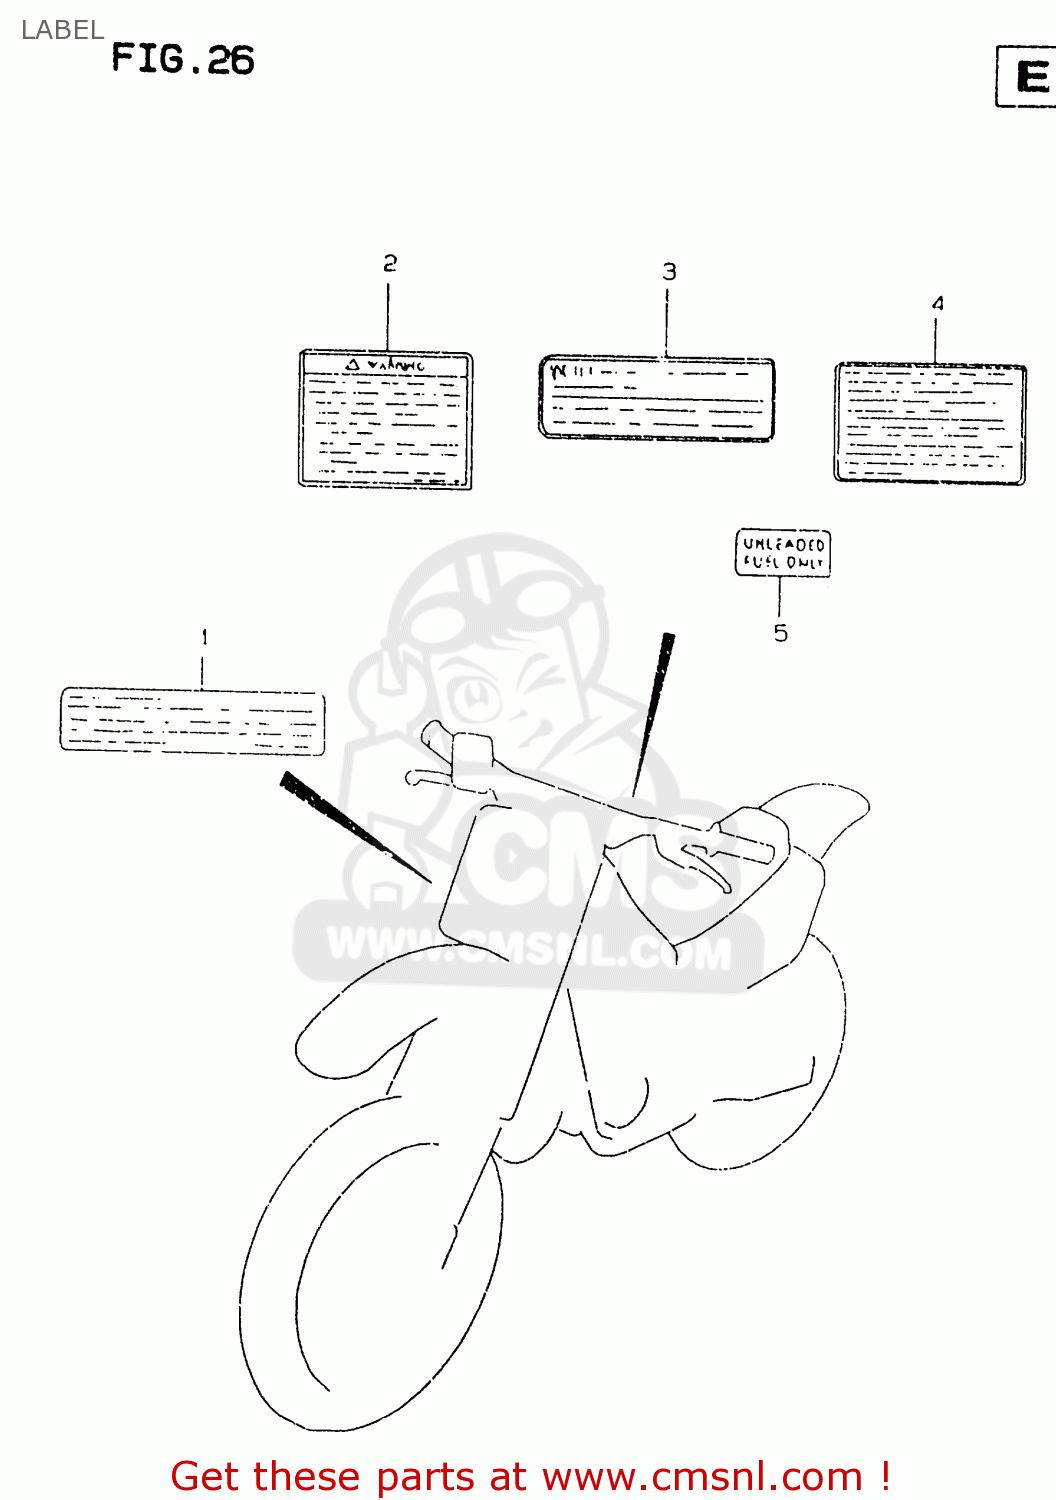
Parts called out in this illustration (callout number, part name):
1	PLATE,WARNING
2	LABEL,WARNING
3	LABEL,WARNING NO.2
4	LABEL,WARNING
5	LABEL,UNLEADED FUEL
6	MANUAL, OWNER'S
